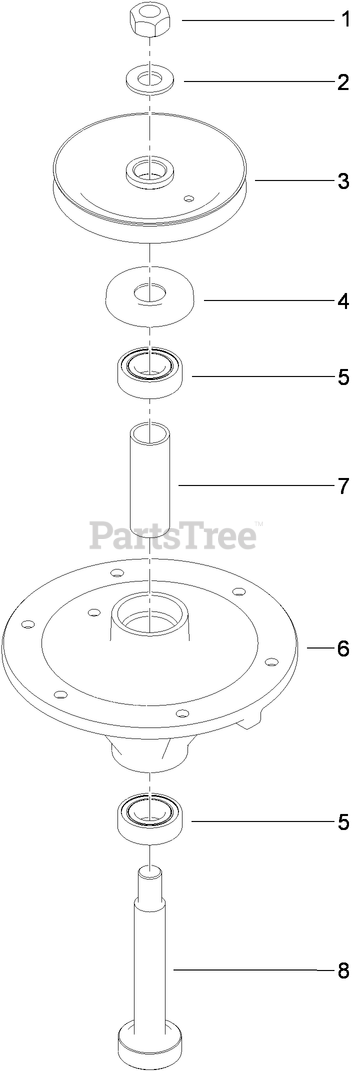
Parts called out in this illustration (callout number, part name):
1	NUT-HEX
2	WASHER
3	PULLEY
4	SHIELD-BEARING
5	BEARING-BALL
6	HOUSING-SPINDLE
7	SPACER-BEARING
8	SHAFT-SPINDLE
